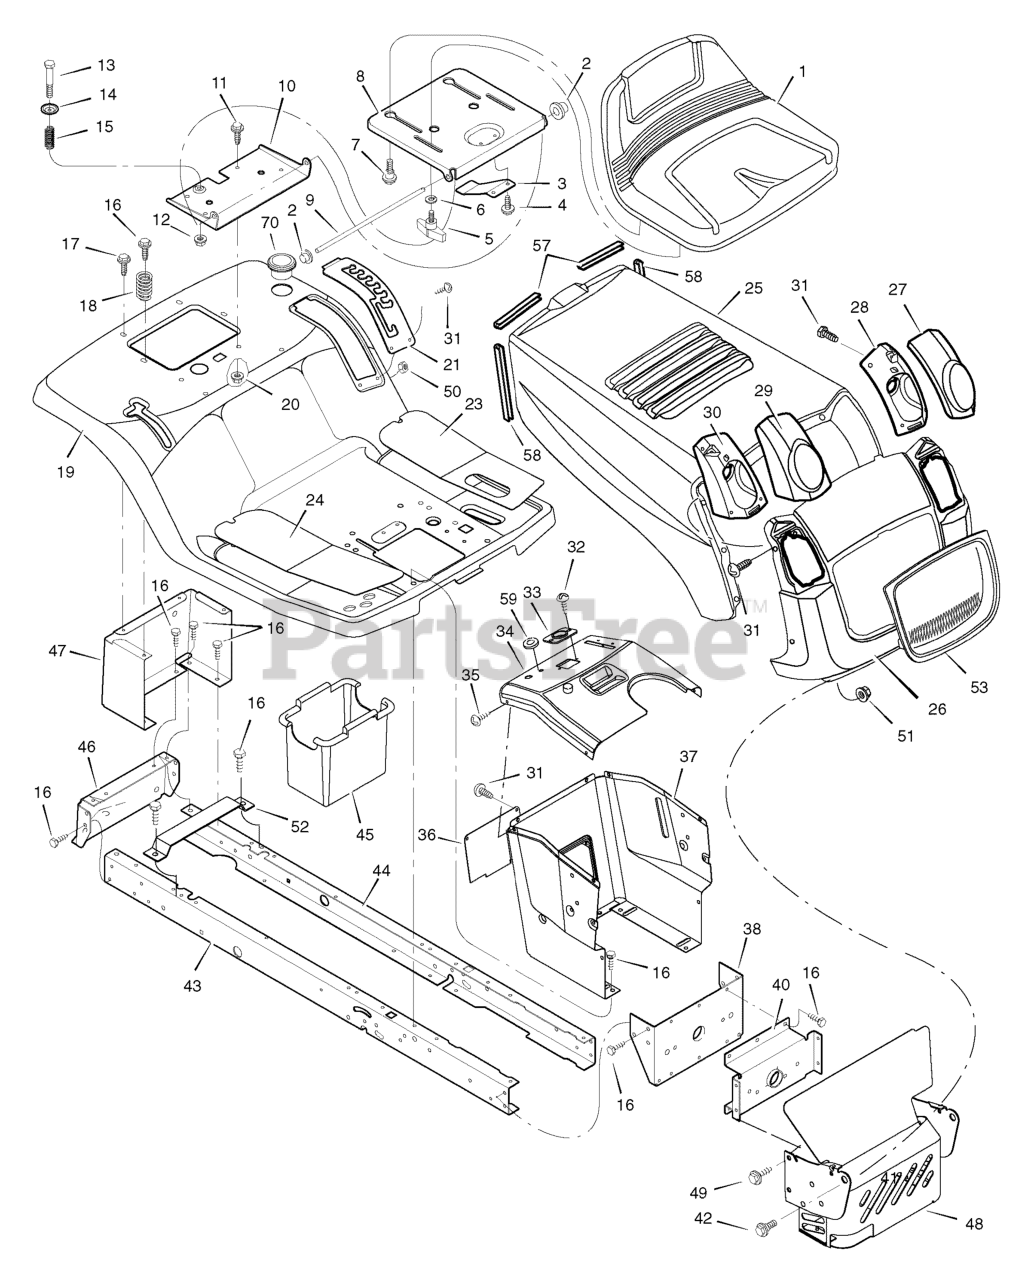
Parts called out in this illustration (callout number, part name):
1	Seat
2	Cap, Push 0n
5	Bolt, Wing
6	Washer
7	Bolt, Shoulder
8	Support, Seat
9	Rod, Pivot
10	Bracket, Pivot
11	Bolt
13	Bolt, Shoulder
20	Nut
21	Plate, Index Detent
23	Mat, Left
24	Mat, Right
27	Lens, Left
28	Assembly, Left Headlamp Housing
29	Lens, Right
30	Assembly, Right Headlamp Housing
33	Bearing, Steering
34	Dash
36	Panel, Access
37	Support, Dash
38	Bracket, Rear Hanger
40	Axle, Hanger
42	Bolt
43	Frame, Right
44	Frame, Left
45	Container, Battery
46	Plate, Hitch
47	Panel, Rear
48	Shield, Heat
51	Nut
52	Support, Battery
53	Insert, Grille
57	Trim, Hood (3.75")
58	Trim, Hood (6.5")
59	Grommet, Parking Brake
70	Holder, Cup
